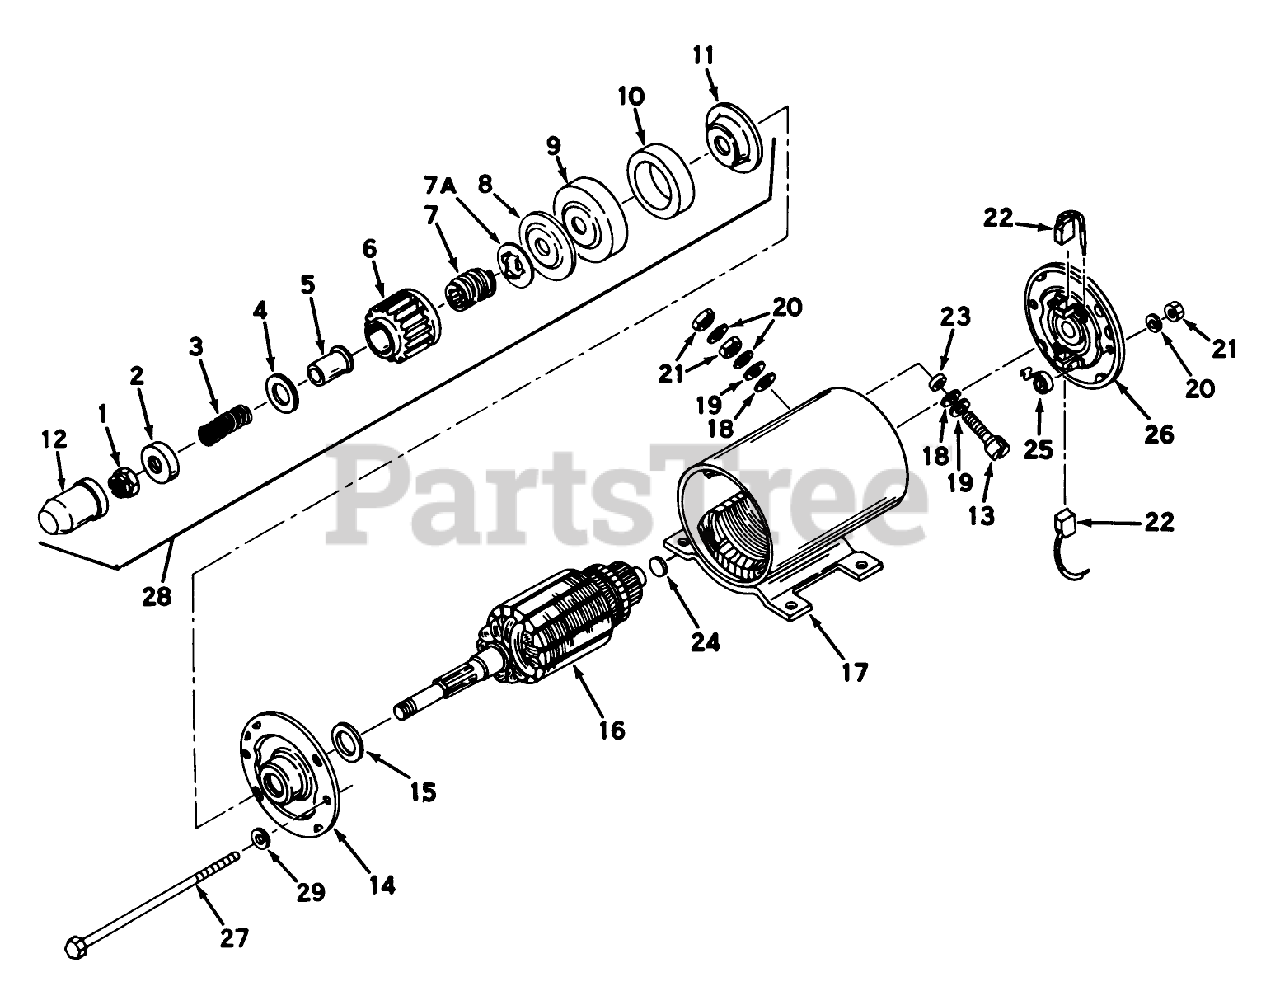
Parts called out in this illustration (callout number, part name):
1	Nut, Hex
2	Setscrew
3	Spring, Anti-Drift
4	Washer, Pinion
5	Sleeve, Anti drift
6	Gear, Pinion
7	Shaft, Screw
7A	Stopper, Screw
8	Washer, Thrust
9	Cap, Cushion
10	Cushion, Rubber
11	Washer, Thrust
13	Bolt, Terminal
14	Cap Assy., Drive end (Incl. Bearing)
15	Washer, Spacing (.024 Thick)
15	Washer, Spacing (.008 Thick)
16	Armature
17	Housing Assy. (Incl. pole shoes, field coils, terminal post, straight mounting bracket, Nos. 18 thru 21)
18	Washer, Insulating
19	Washer
20	Washer, Lock
21	61710/VAR.HILLER AT
22	Brush Spring Kit
23	Bushing, Insulating
24	Washer, Spring
25	Spring, Brush
26	End Cap Assy., Commutator
27	Bolt, Thru
28	Drive Assy., Complete (Incl. Nos. 1 thru 12)
29	Washer
